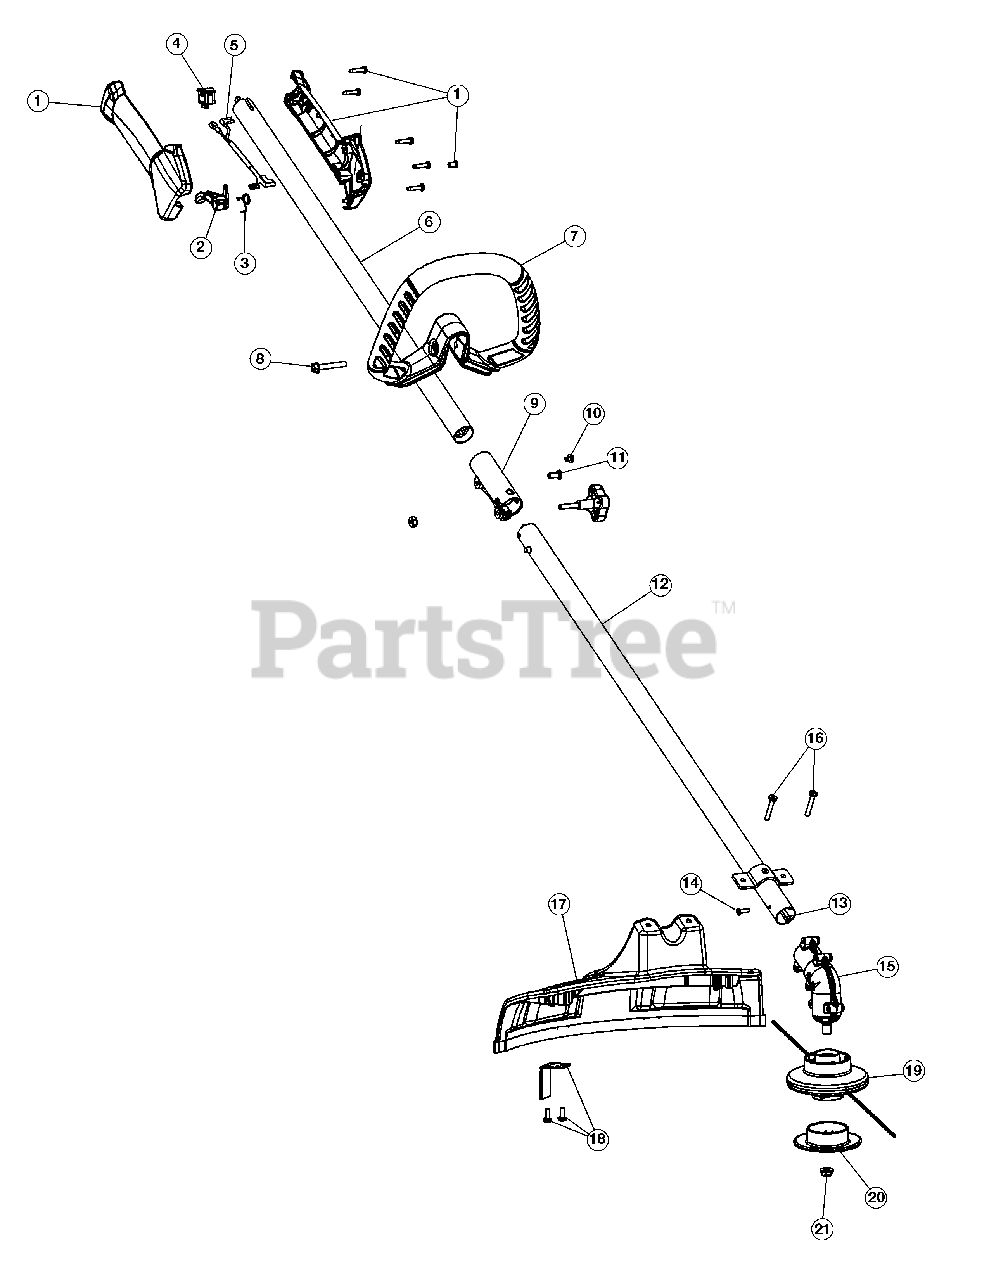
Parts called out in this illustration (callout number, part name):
1	Throttle Housing Assembly (Incl. 2 - 4)
2	Throttle Trigger
3	Throttle Trigger Spring
5	Throttle Cable Assembly
6	Upper Drive Shaft Housing Assembly
7	D-Handle Assembly (Incl. 8)
9	Split Boom Coupler (Incl. 10 and 11)
11	Knob, Adjustment
11	Nut, Retaining
12	Lower Drive Shaft Housing Assembly
13	Lower Flexible Drive Shaft
14	Anti-Rotation Screw
15	Gear Box Assembly (Incl. 14, 19 - 21)
16	Shield Mounting Screw
17	Shield Assembly (Incl. 18)
18	Blade Assembly
19	Cutting Head Assembly (Incl. 20 and 21)
